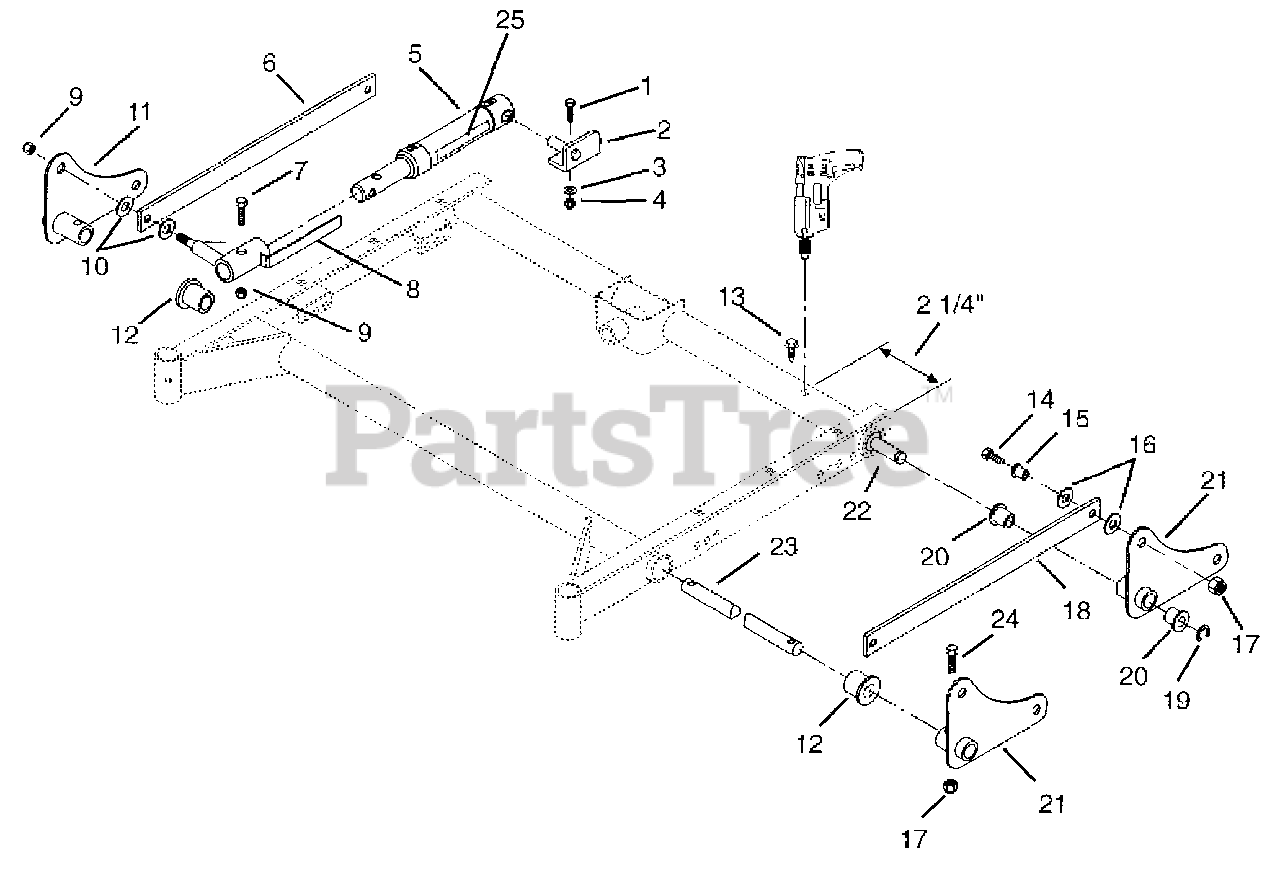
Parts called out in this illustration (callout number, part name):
1	Bolt-Hex .38-16 x 1.50 Grade 5
2	Deck Lift-Rear Deck Bracket-Left Hand
3	Washer-Flat-Steel .438 x 1.0 x .083
4	Nut-Locking-Center .375-16 Grade 2
5	Cylinder-Hydraulic
6	Link Bar-Right Hand Deck Lift
7	Bolt-Hex .50-13 x 2.00 Grade 5
8	Lift Ram-Terminal Pin
9	Nut-Locking-Center .50-13 Grade 5
10	Washer-Hardened-Steel-Thrust .515 x .97 x .062
11	Lift-Arm-Weldment
12	Bushing-Flange 1.020 x 1.385 x .75 x 1.75
13	Screw-Tapping .25-20 x .50
14	Bolt-Hex .31-18 x 1.25 Grade 5
15	Bushing-Flange .325 x .500 x .513 x .875
16	Washer-Flat-Steel .312 x .734 x .065 (19527)
17	Nut-Locking-Center .31-18
18	Link Bar-Deck Lift
19	Ring-Retaining-External .750 x .050
20	Bushing-Flange .762 x 1.0 x .580 x 1.48
21	Lift-Arm-Weldment-Left Hand
22	Shaft-Stub 50" Lift
23	Cross-Shaft 50" Deck Lift
24	Bolt-Hex .31-18 x 1.75 Grade 5
25	Decal-Deck Lift
